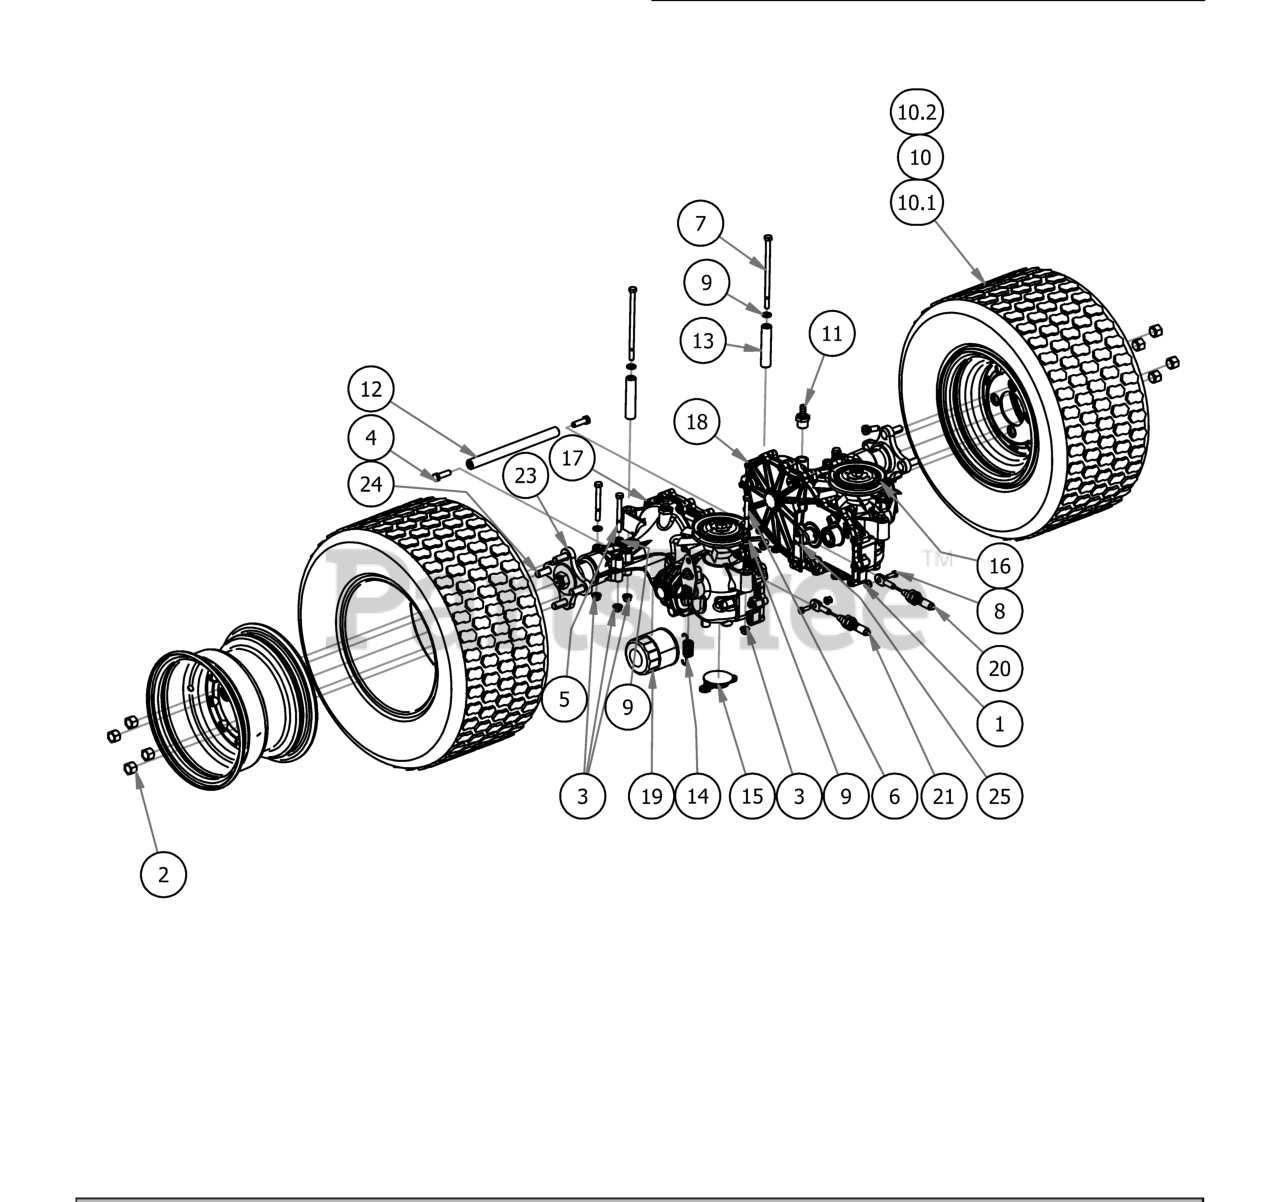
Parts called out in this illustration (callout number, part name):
1	1/4-20 Nylon Insert flange Nut
2	Acorn Lug Nut
3	5/16" Nylon Flange Nut
4	3/8'' x2'' Hex Bolt
5	5/16" x 3" Hex Bolt
6	5/16" x 2 1/2" Bolt
7	5/16" x 6" Bolt
8	1/4" x 3/4" Hex Bolt
9	5/16" Flat Washer
10	ZT Avenger Tire and Rim Assembly 20x12x10
10.1	ZT Avenger Tire 20x12x10
10.2	ZT Avenger Black Wheel 10x8.5
11	45 degree fitting
12	2017 Transaxle Spacer-ZT
13	2017 Transaxle Spacer
14	Transaxle Spring
15	ZT Transaxle Charge Plate/With O'Ring
16	Fan/Pulley Kit for ZT
17	Right ZT Avenger Transaxle
18	Left ZT Avenger Transaxle
20	Brake Cable,18.5"
21	Brake Cable, 24.5"
